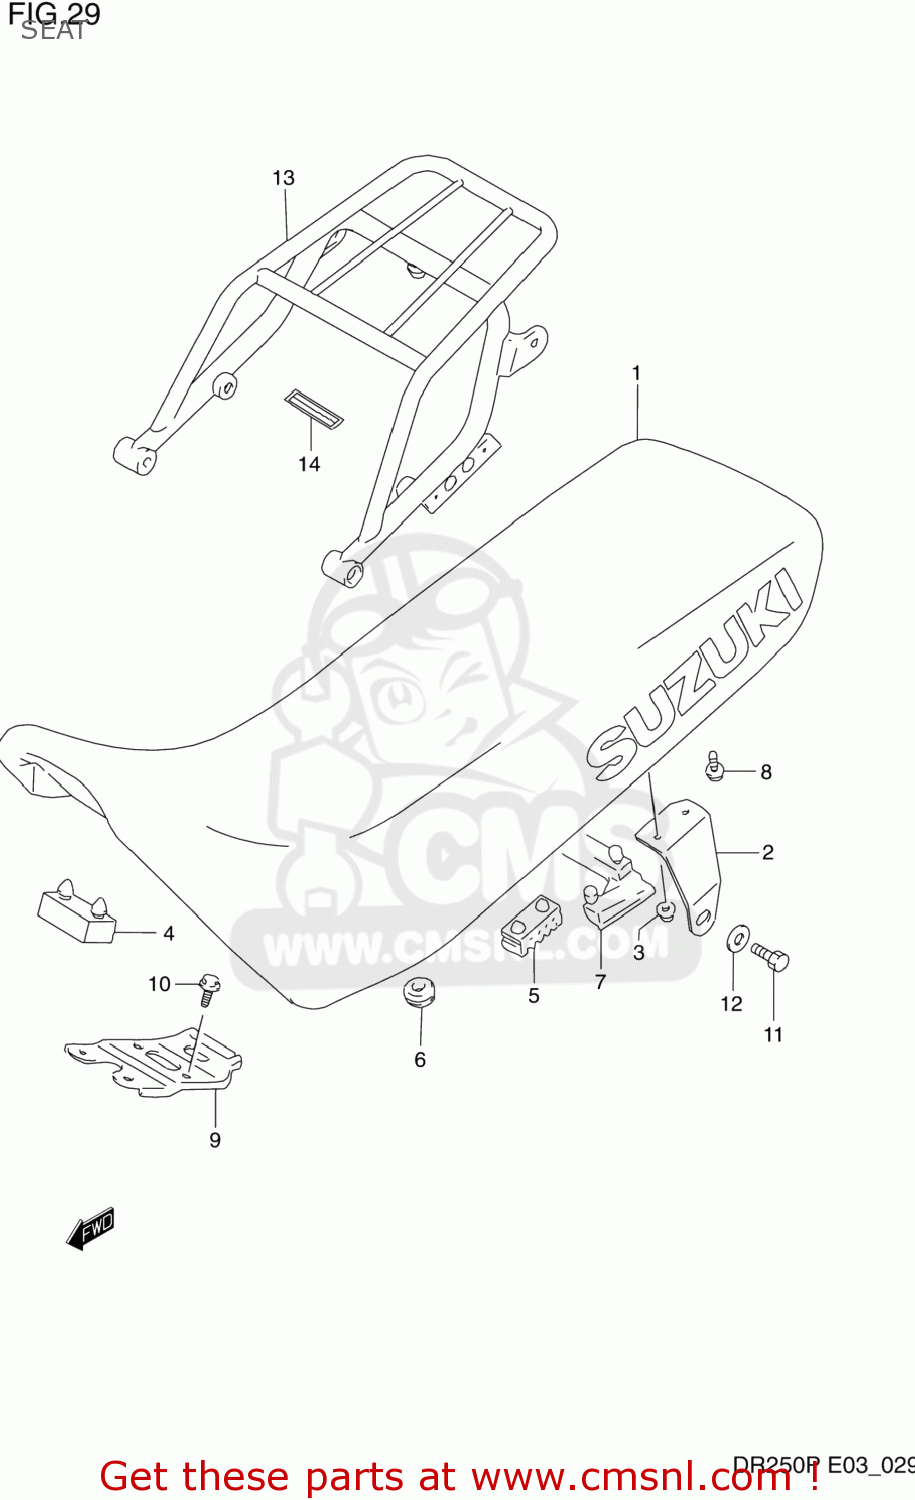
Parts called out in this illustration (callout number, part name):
1	SEAT SET
2	BRACKET,SEAT,R
3	NUT
4	CUSHION
5	CUSHION,SEAT(40X20X15)
6	CUSHION
7	CUSHION
8	BOLT
9	PLATE,SEAT FR HOOK
10	BOLT
11	BOLT
12	WASHER
13	CARRIER
14	LABEL,WARNING
